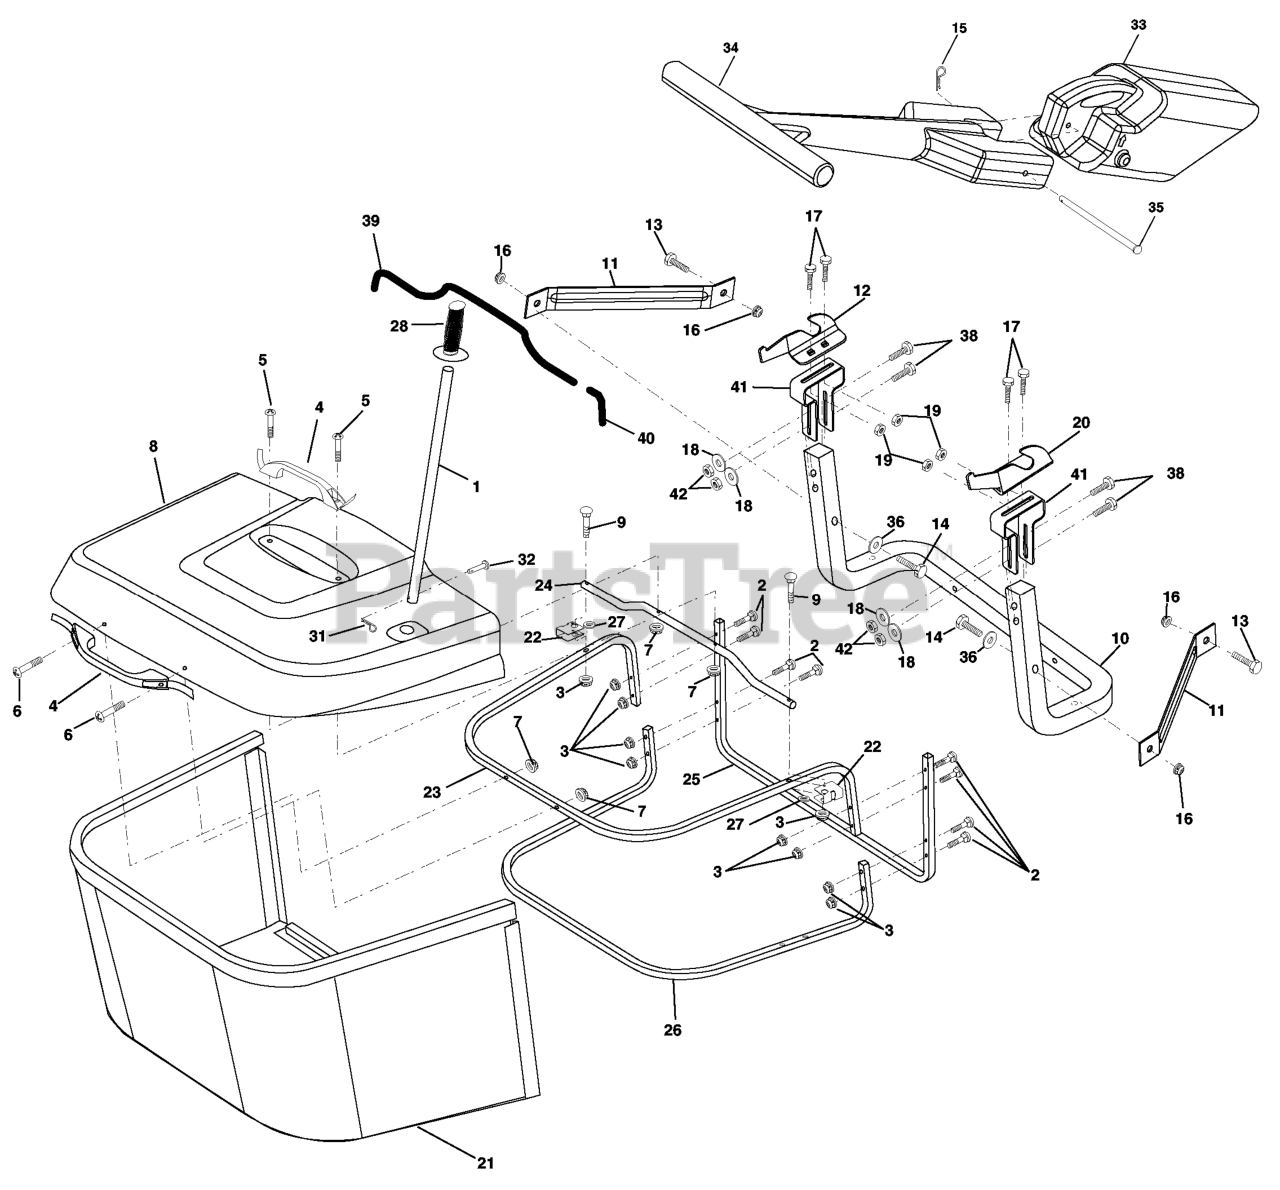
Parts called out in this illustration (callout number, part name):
1	TUBE HANDLE BAGGER
2	Bolt Carriage 1/4-20 x 2.0 Gr.5
3	NUT T
4	HANDLE.BAGGER.W/LVRS.BLK.CRD
5	SCREW.PAN.HEAD
6	REPL BY 532 75 00-29
8	COVER
9	Bolt Carriage 1/4-20 x 2.25d x Gr.5
10	TUBE
11	BRACKET.SUPPORT.UPPER.BAG.CRD
13	BOLT
14	Bolt Hex 3/8-16 x 2-1/2 Gr.5
15	RETAINER-SPRNG RB
16	NUT LOCK FLG 3/8-16 UNC
17	RP BOLT 5/16-18 X3/4 ZN/YEL GR
19	NUT LOCK HEX FLANGE 5/16-18
20	BRACKET
21	BAG
22	BRKT.SIDE.BAG.CRD
23	TUBE.UPPER.BAG.CRD
24	TUBE.PIVOT.BAG.CRD.BLACK
26	TUBE.LOWER.BAG.CRD
28	Grip Handle Black
31	RETAINER M
32	RIVET,DRILLED
33	PLUG.MULCHER.92 CRD
34	HANDLE.MULCHER.92.CRD (2 2)
36	WASHER
38	BOLT.5/16-18X2.5
39	TRIM
40	TRIM
41	BRKT.VERT.ADJ.BAGGER.CRD
42	NUT.71038.31-18.HEX.NYLOCK
